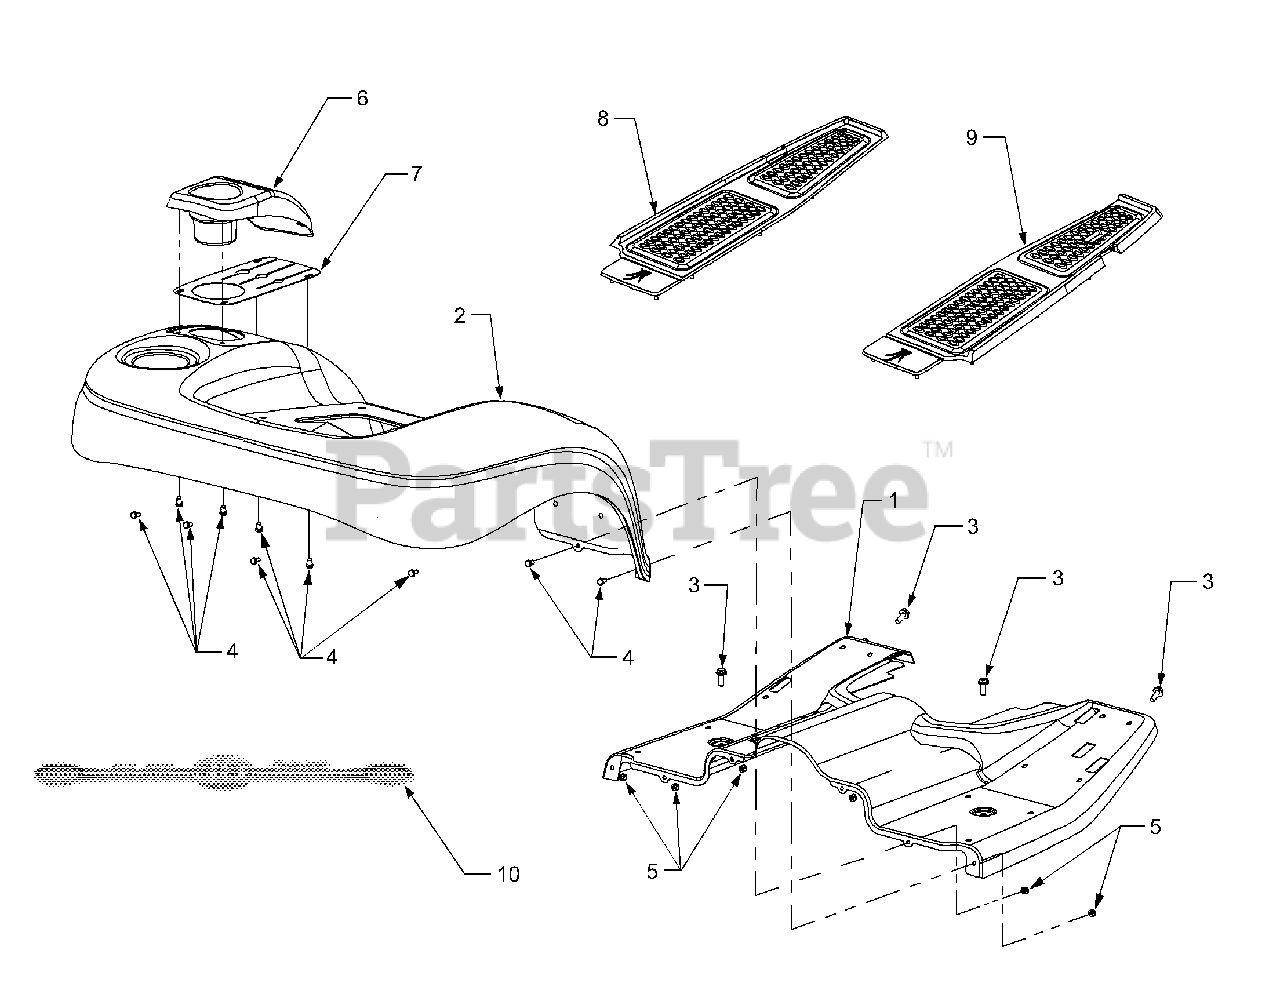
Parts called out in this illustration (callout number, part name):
1	Running Board
2	Fender
3	Screw, Hex Wash. Hd. Tapp 5/16-18 x 1.0
4	Screw, Hex Cap, 1/4-20 x .5 GR5
5	Nut, Hex Lock, 1/4-20
6	Cover, Lift Lever
7	Flap, Lift Lever
8	Pad. Floor LH
9	Pad. Floor RH
10	Graphic, 40th Anniversary Fender
